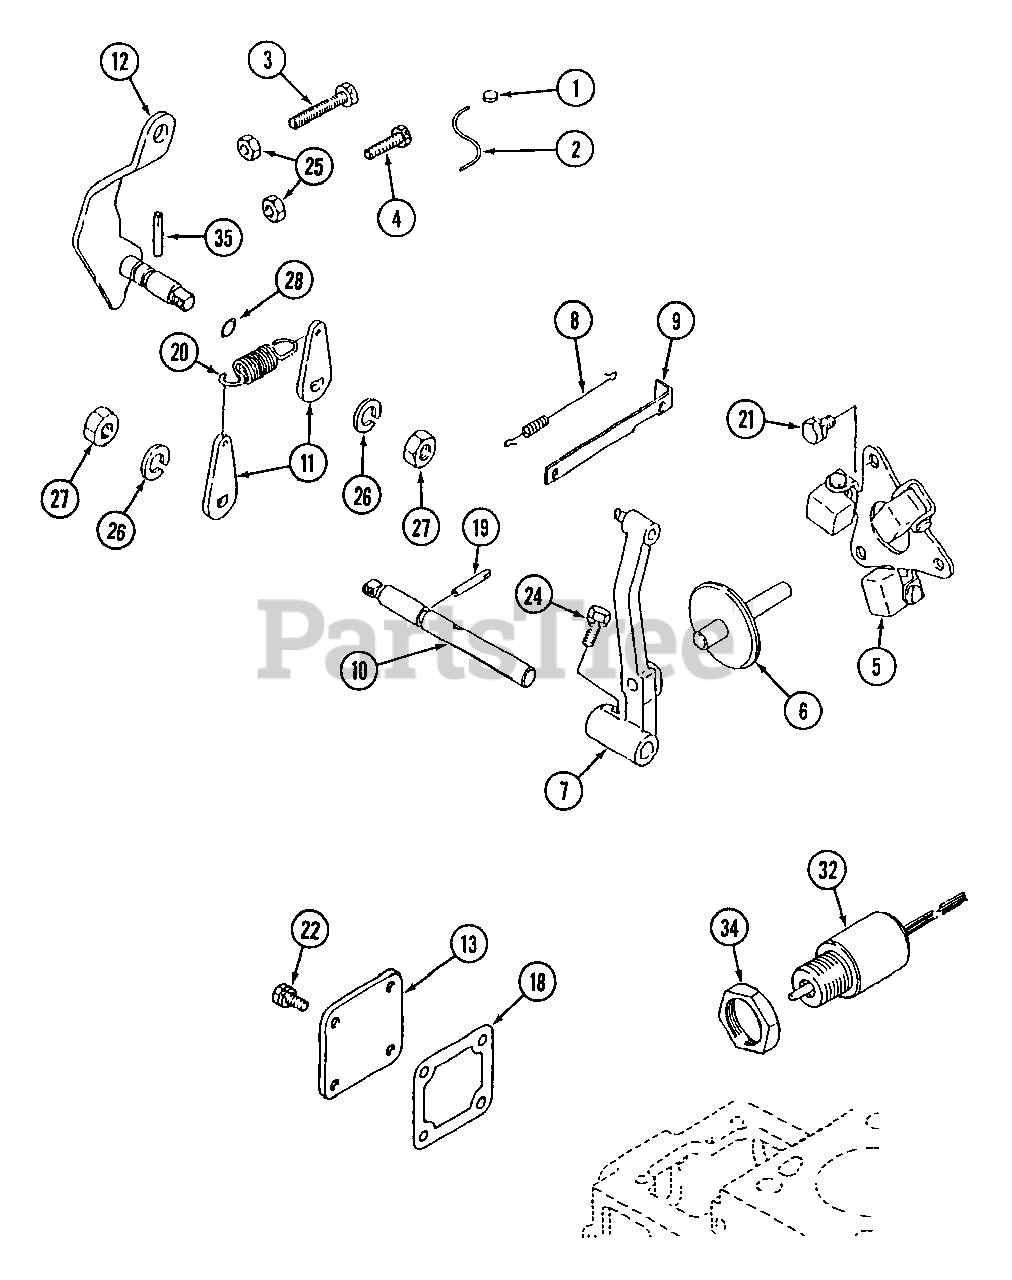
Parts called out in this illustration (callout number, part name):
1	Metal, Sealing
3	Bolt, High Idle Set
4	Bolt, Idle Set
5	Weight Ass'y., Governor
6	Shaft Ass'y., Sliding
7	Lever Ass'y., Governor
8	Spring, Tie Rod
9	Rod, Tie
10	Shaft, Governor
11	Lever, Governor Spring
12	Lever, Speed Control
13	Cover Ass'y., Tie Rod
18	Gasket, Cover
19	Pin, Grooved
20	Spring, Governor
21	Bolt, w/Washer
22	Bolt, w/Washer
24	Bolt, w/Washer
26	Washer, Spring
32	Solenoid & Nut
35	Pin, Grooved
